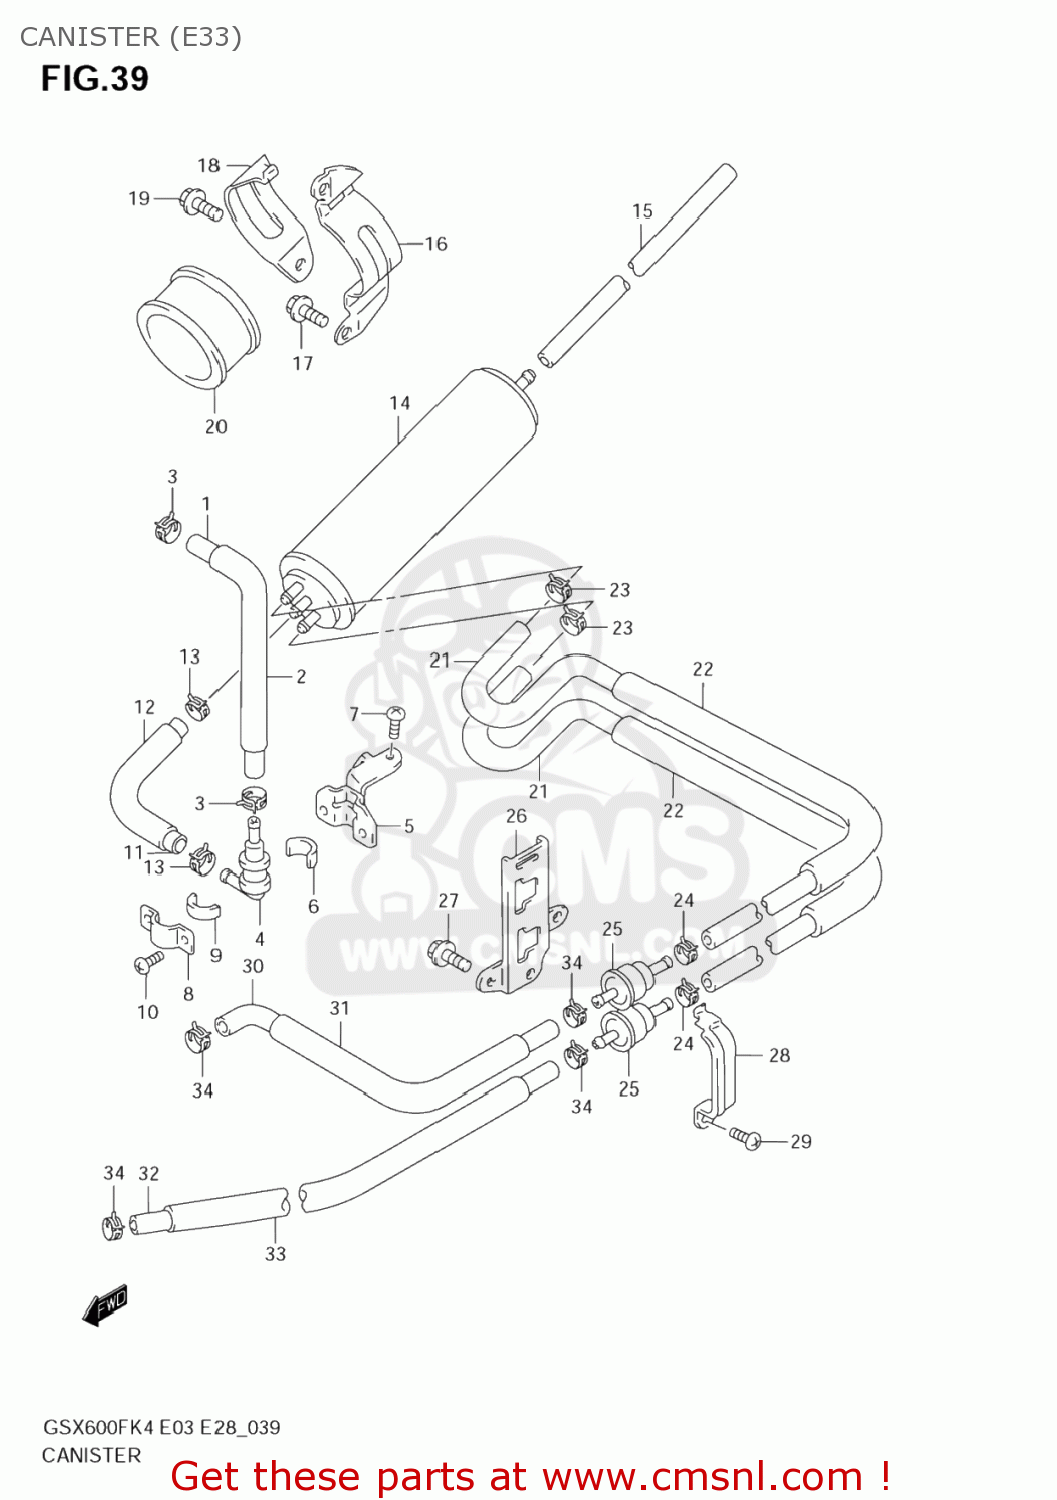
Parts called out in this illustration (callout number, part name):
1	HOSE(5.4X11.4X600)
2	PROTECTOR(14.5X15.5X600)
3	CLIP
4	VALVE,FUEL TANK BREATHER
5	PLATE,BREATHER VALVE
6	CUSHION
7	SCREW
8	PLATE,FUEL TANK BREATHER NO.2
9	CUSHION
10	SCREW 6X12
11	HOSE,VALVE & CANISTER CHARGE
12	PROTECTOR(14.5X15.5X600)
13	CLIP
14	CANISTER ASSY,CHARCOAL
15	HOSE(7X12X600)
16	BRACKET,CANISTER MOUNTING
17	BOLT
18	HOLDER,CANISTER
19	SCREW 6X12
20	CUSHION,CANISTER
21	HOSE,CSTR & PURGE VALVE
22	PROTECTOR(14.5X15.5X600)
23	CLIP
24	CLIP
25	VALVE,CANISTER PURGE
26	BRACKET,CANISTER PURGE VALVE
27	BOLT
28	HOLDER,CANISTER PURGE
29	SCREW
30	HOSE(5.4X11.4X2000)
31	HOSE
32	HOSE(5.4X11.4X2000)
33	PROTECTOR(14.5X15.5X600)
34	CLIP
